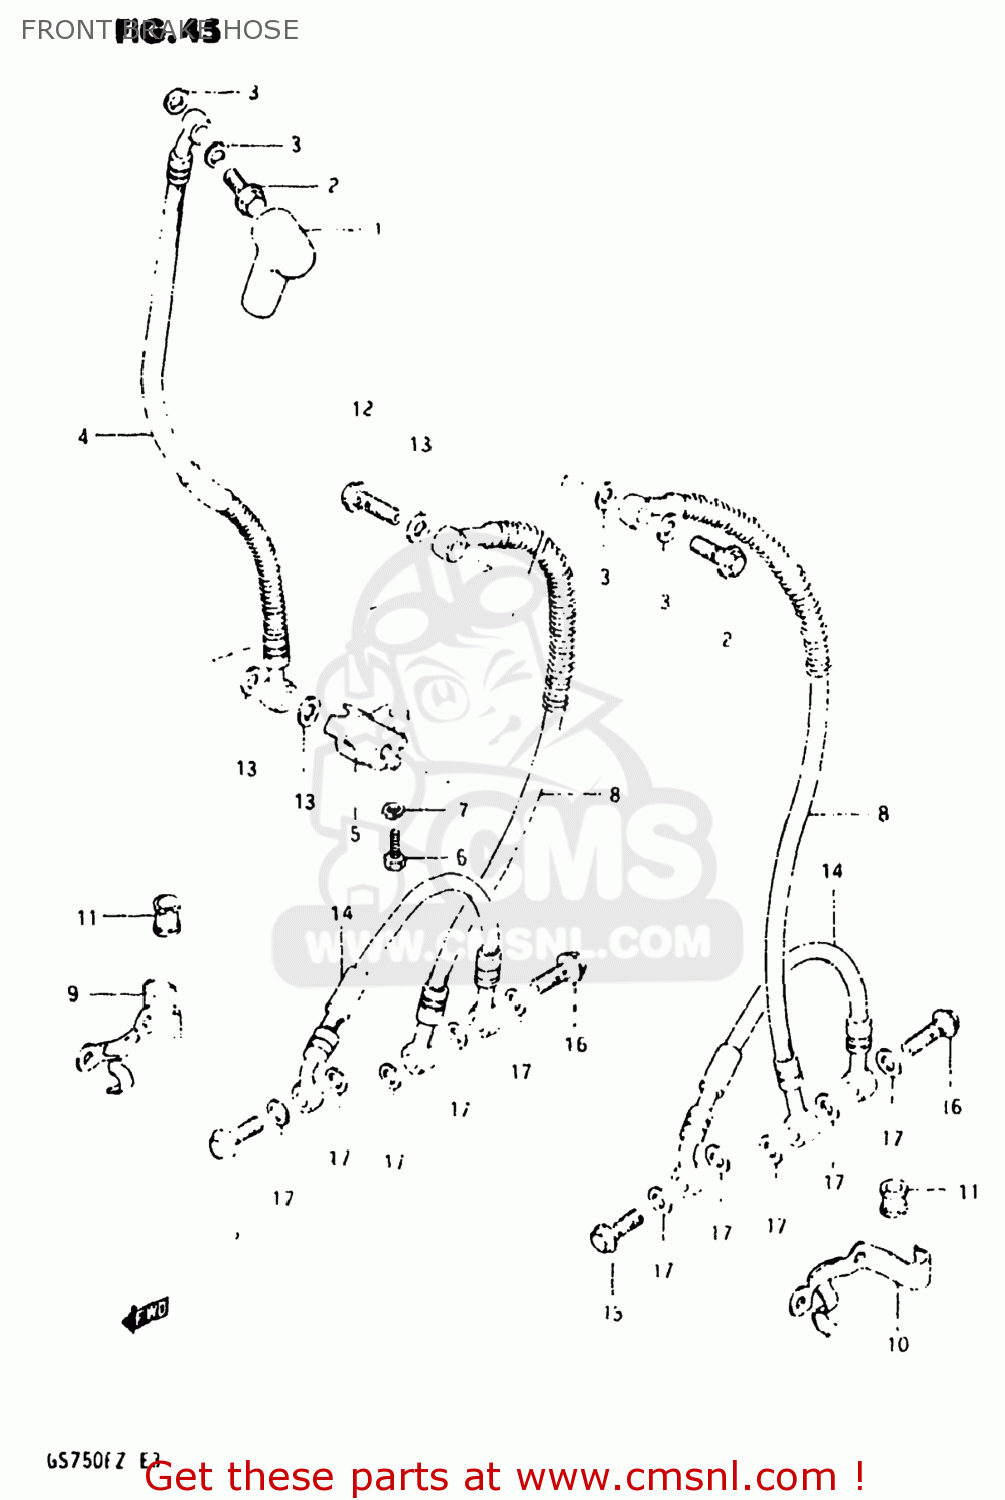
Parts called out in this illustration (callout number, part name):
1	BOOT,MASTER CYLINDER
2	BOLT,UNION
3	WASHER
4	HOSE,FRONT BRAKE
5	JOINT,BRAKE HOSE
6	BOLT
7	LOCK WASHER
8	HOSE,FRONT BRAKE
9	CLAMP,FRONT BRAKE HOSE
10	CLAMP,FRONT BRAKE HOSE
11	BUSH,BRAKE HOSE GUIDE,NO.2
12	BOLT,UNION
13	WASHER
14	HOSE,ANTI-NOSE DIVE
15	BOLT,UNION
16	BOLT,UNION
17	WASHER
